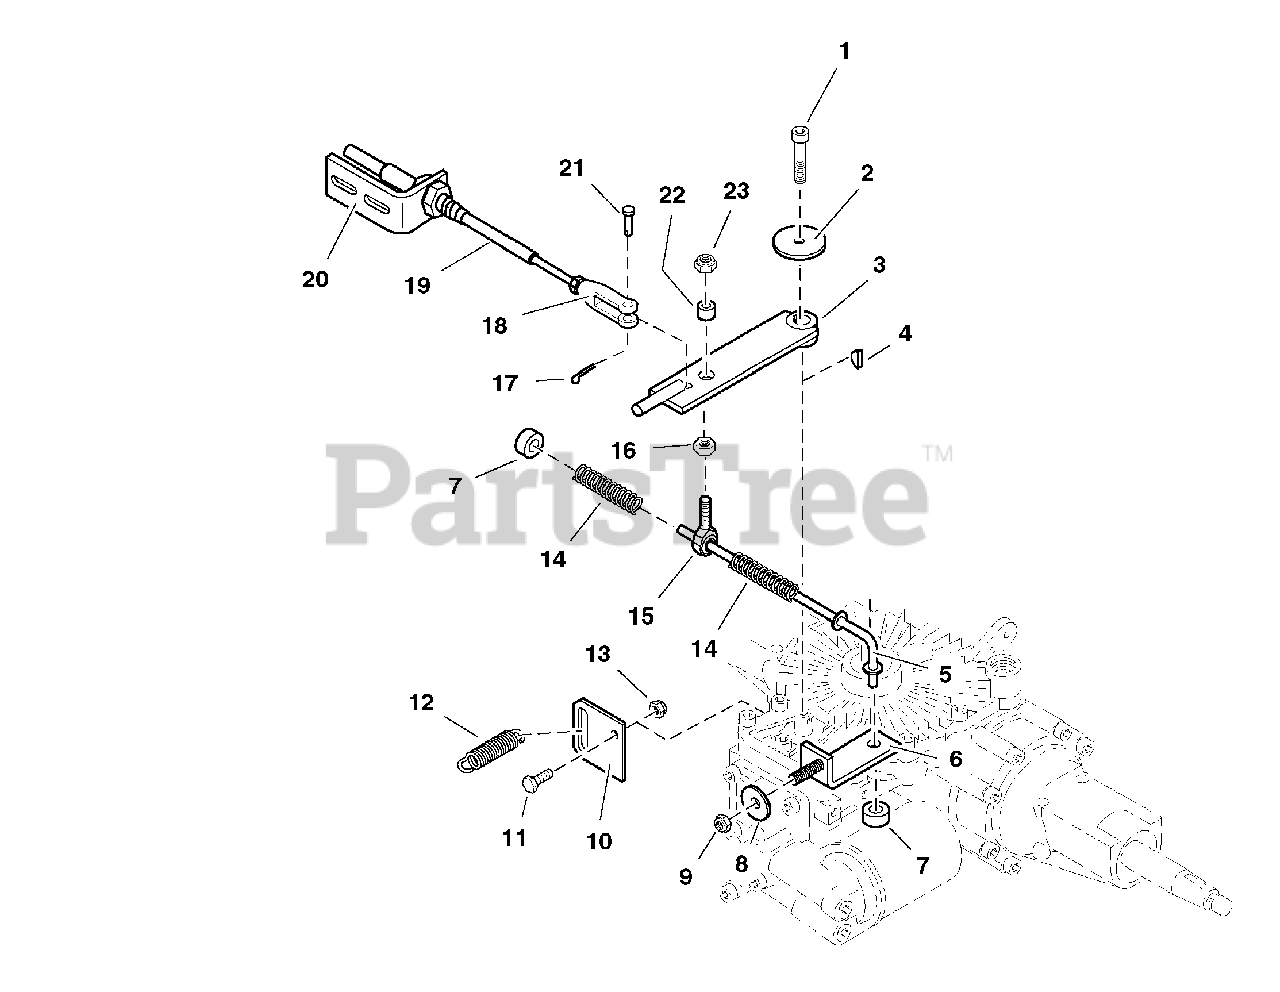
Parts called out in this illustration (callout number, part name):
1	CAPSCREW, Allen Hd, 1/4-20 x 1-1/2
2	WASHER, .265 x 1.50 x .109
3	TRANSMISSION CONTROL ARM
4	KEY, #3 Woodruff
5	NEUTRAL SPRING ROD
6	NEUTRAL BRACKET
7	COLLAR, Set, 5/16
8	WASHER, Fender, 5/16
9	NUT, Hex, Nylon Lock, 5/16-18
10	DUMP VALVE LEVER
11	BOLT, 1/4-20 X 1", GD
12	SPRING, Extension
13	NUT, Hex, Nylon Lock, 1/4-20
14	SPRING, Compression
15	BALL JOINT, 3/8-24 Male
16	NUT, Hex, 3/8-24
17	PIN, Cotter
18	CLEVIS, Plastic, 1/4-28
19	SPEED CONTROL CABLE
20	CABLE BRACKET
21	PIN, Clevis
22	PIVOT SLEEVE
23	NUT, Hex, Nylon Lock, 3/8-24
